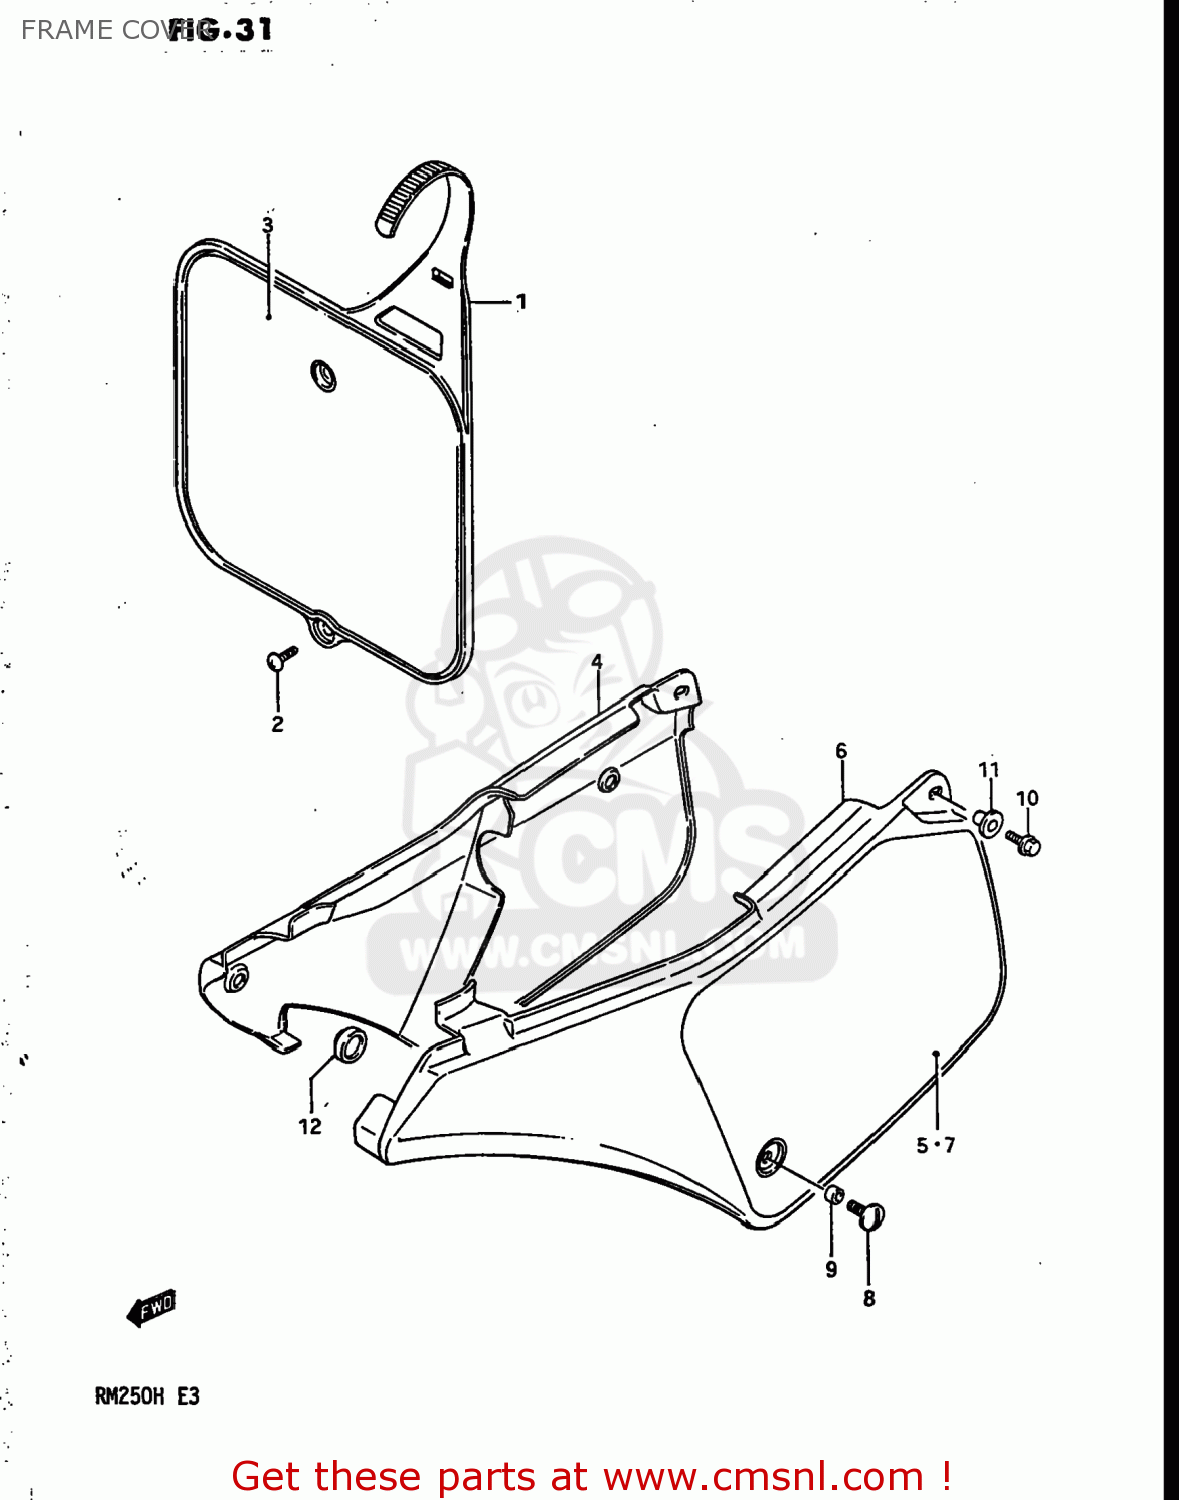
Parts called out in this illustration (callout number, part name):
1	PLATE,NUMBER,FRONT
2	SCREW
3	EMBLEM,FRONT NUMBER PLATE
4	COVER,FRAME,RIGHT
5	EMBLEM
6	COVER,FRAME,LEFT
7	EMBLEM,FRAME COVER,LEFT
8	SCREW(6X14)
9	SPACER (6.1X8X3.5)
10	BOLT
11	WASHER
12	CUSHION
